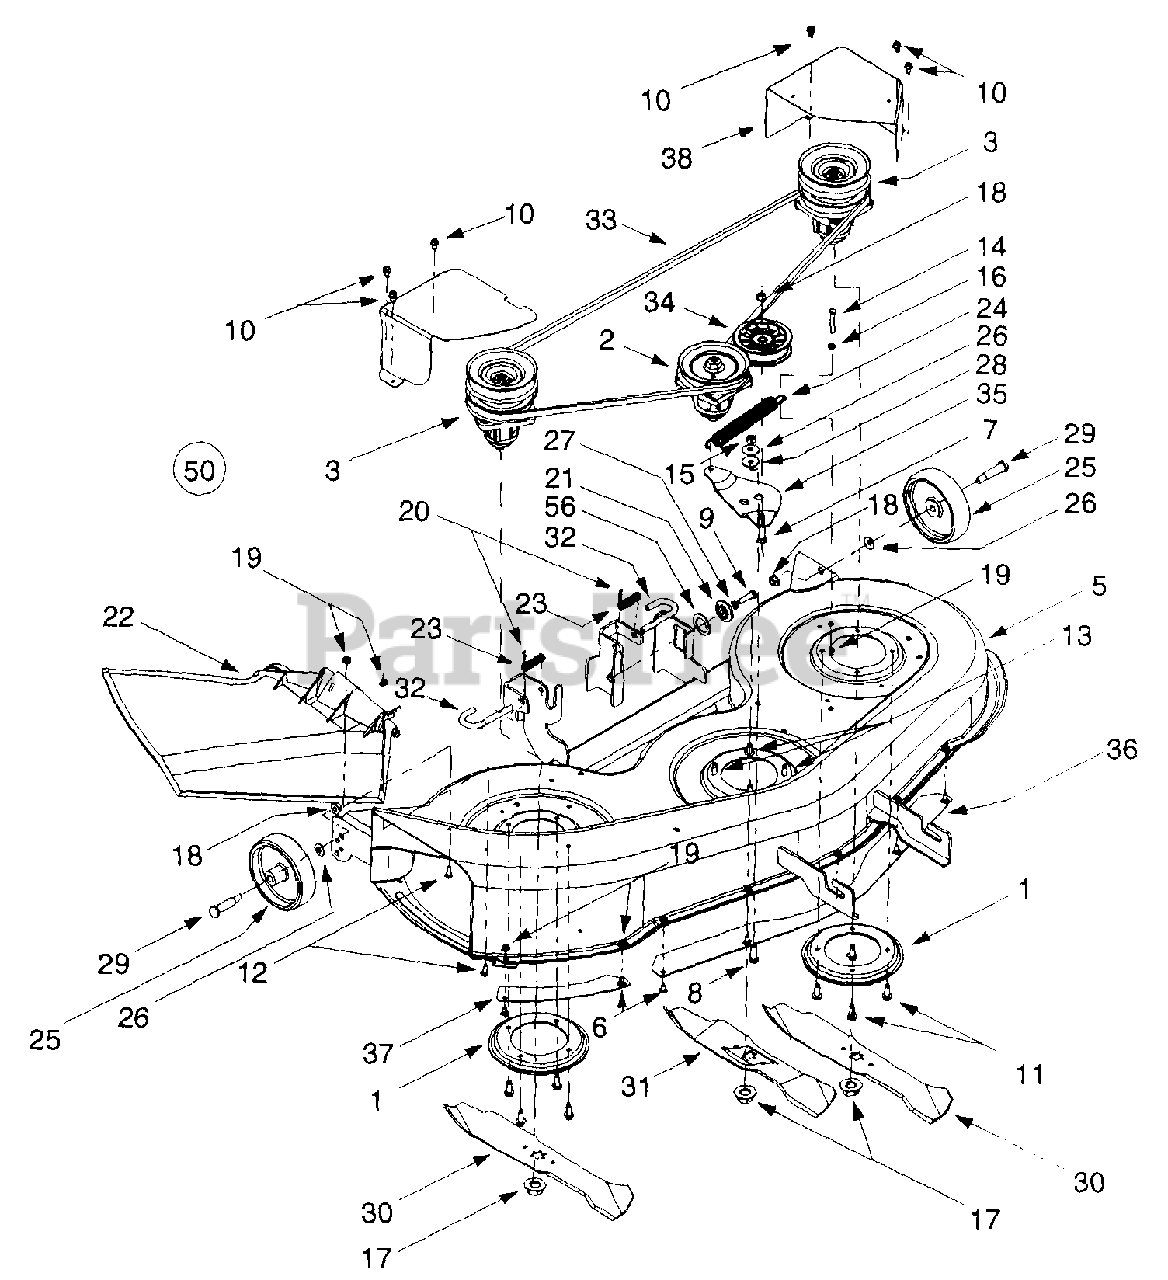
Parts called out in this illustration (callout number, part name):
3	Double Pulley Spindle Assembly
5	46-inch Deck Shell
6	Carriage Screw, 1/4-20 x .5
7	Hex Cap Screw, 3/8-16 x 1.75
8	Hex Cap Screw, 3/8-16 x 1.0
9	Hex Cap Screw, 5/16-18 x 1.25
10	Self Tapping Screw, 1/4-20 x .5
11	Self Tapping Screw, 5/16-18 x .875
12	Hex Cap Screw, 1/4-20 x .62
13	Self Tapping Screw, 5/16-18 x .75
14	Hex Cap Screw, 1/4-20 x 1.62
15	Hex Nut, 3/8-24
16	Center Lock Nut, 1/4-20
17	Hex Flange Nut, 5/8-18
18	Flange Lock Nut, 3/8-16
19	Hex Flange Lock Nut, 1/4-20
20	Internal Cotter Pin, .072 x 1.12
21	Deck Adjustment Gear
22	Side Discharge Chute Assembly
23	Compression Spring, .406 x .531 x 1.75
24	Extension Spring, .91 x 7.33
25	Deck Wheel, 5 x 1.38
26	Bell Washer, .401 x .87 x .063
27	Lock Washer, 5/16
28	Shoulder Spacer, .625 x .169
29	Shoulder Spacer, .498 x 1.53
30	Three-in-one Blade, Star Center, 16.28
31	Three-in-one Blade, Star Center, 14.88
32	Deck Release Pin
33	Deck Belt
34	Flat Idler Pulley, 3.5 OD
50	46-inch Deck Assembly Complete
56	Flat Washer, 1.03 x 1.62 x .030
